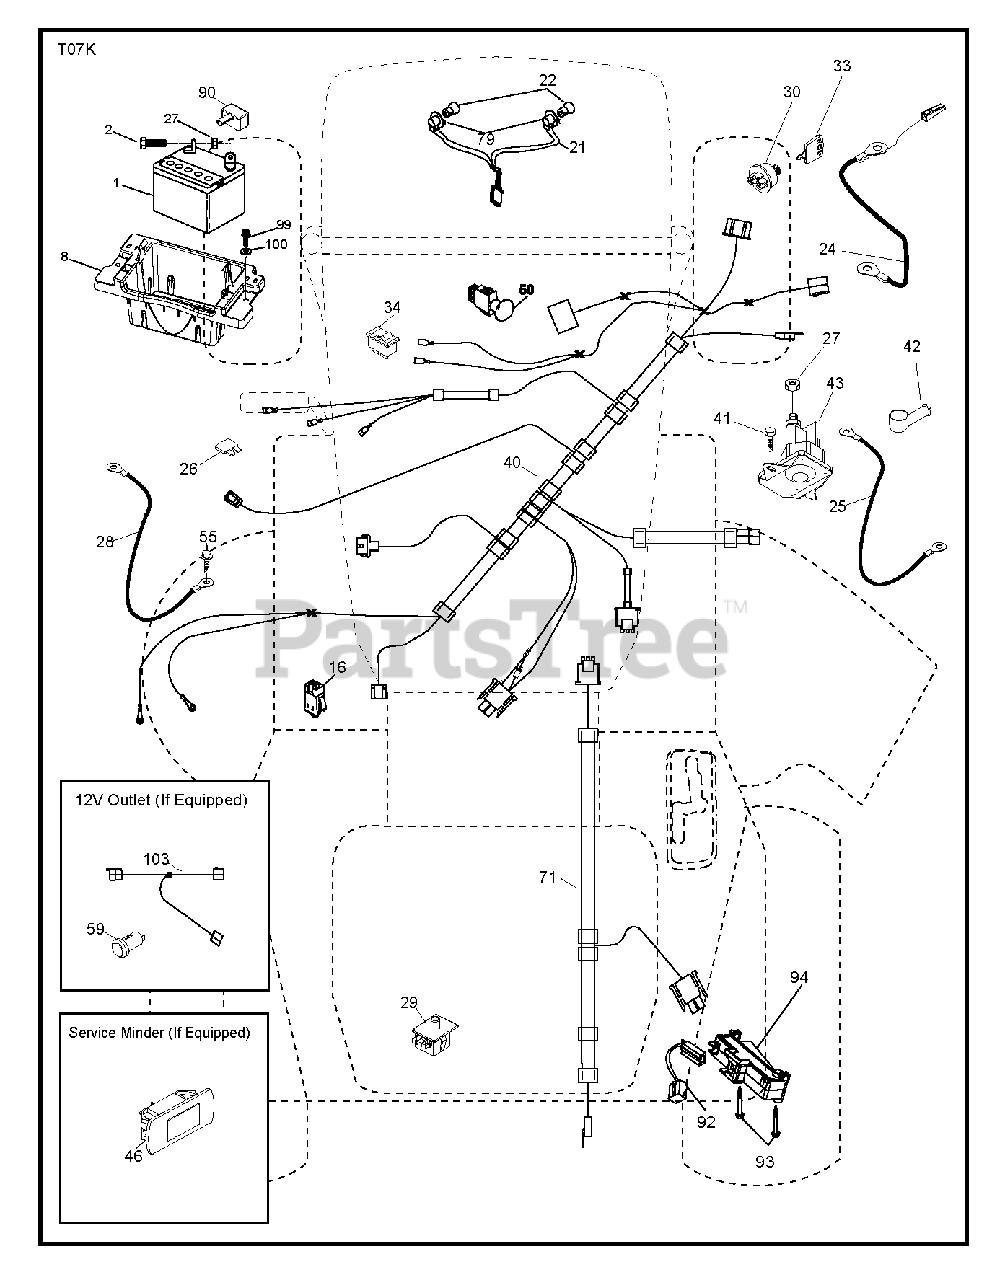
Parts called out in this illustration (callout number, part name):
1	REPL BY 532 12 38-99
2	BOLT.HEX.1/4.X.3/4.DICHROMATE
8	TRAY.BATTERY BOX.FRONT
16	SWITCH INTERLOOK PUSH-IN
21	HARNESS.LIGHT W/4152J BULBS
22	LIGHTBULB
24	Battery Cable with Wire, Front 8 Ga 8
25	CABLE.STARTER.6G.BL/RED.17.5
26	FUSE 20AMP
27	NUT
28	Ground Cable, 21" Black 8 Ga 90T
29	SWITCH.SEAT.DP W/RAMPS
30	SWITCH.IGN.DELTA.W.LGH.ROS
33	KEY.CHAIN.BLISTER.PACK.GEN.INT
34	SWITCH LT
40	HARNESS.IGN.DASH.HUQ/P
41	SCREW
42	TERMINAL COVER
43	SOLENOID.W/BRASS.PLUNGER
46	Hour Meter Gauge
50	PTO SWITCH
55	SCREW 5/16"
71	HARNESS-CHASSIS SUB
79	BULB HOLDER ASM.
90	COVER.TERMINAL.BATTERY
92	HARNESS.PIGTAIL.CONSLE
93	SCREW.PLASTITE
94	MODULE.REVERSE.ROS
99	SCREW HEXWSHR 1/4-20X3/4
